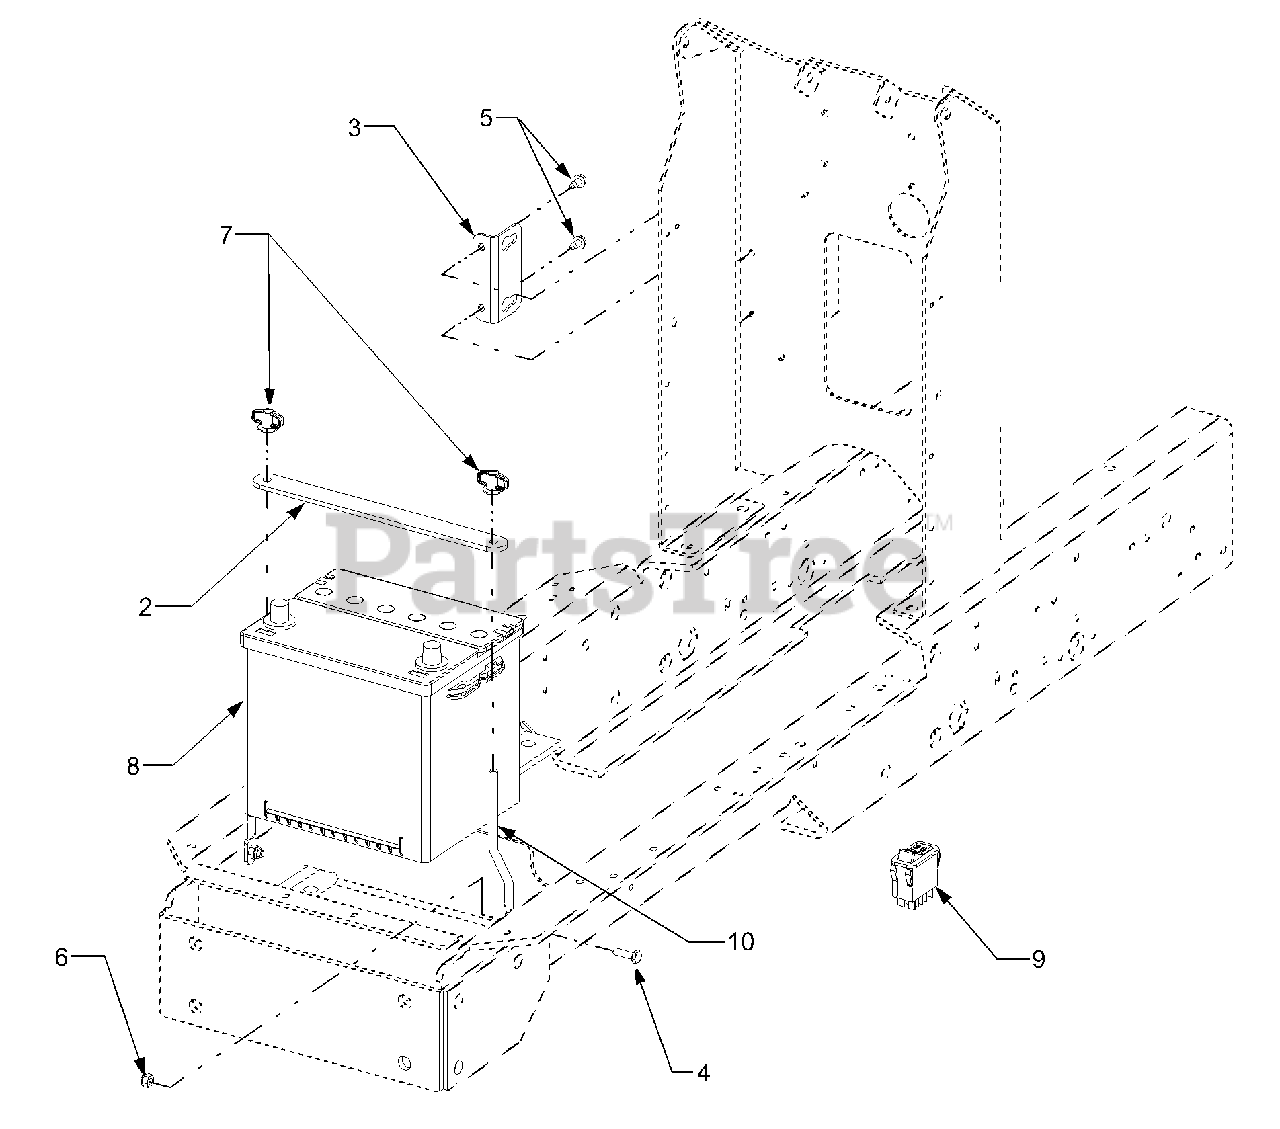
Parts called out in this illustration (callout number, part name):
2	Strap, Battery Holddown
5	Screw, Hex Wash Hd. Tapp 1/4-20 x .5
6	Nut, Hex Nylon Insert Lock, 1/4-20
7	Nut, Wing w/Bell Washer, 5/16-18
8	Battery, 500 cca Dry
9	Switch, PTO Reverse Override
10	Rod, Battery Holddown
